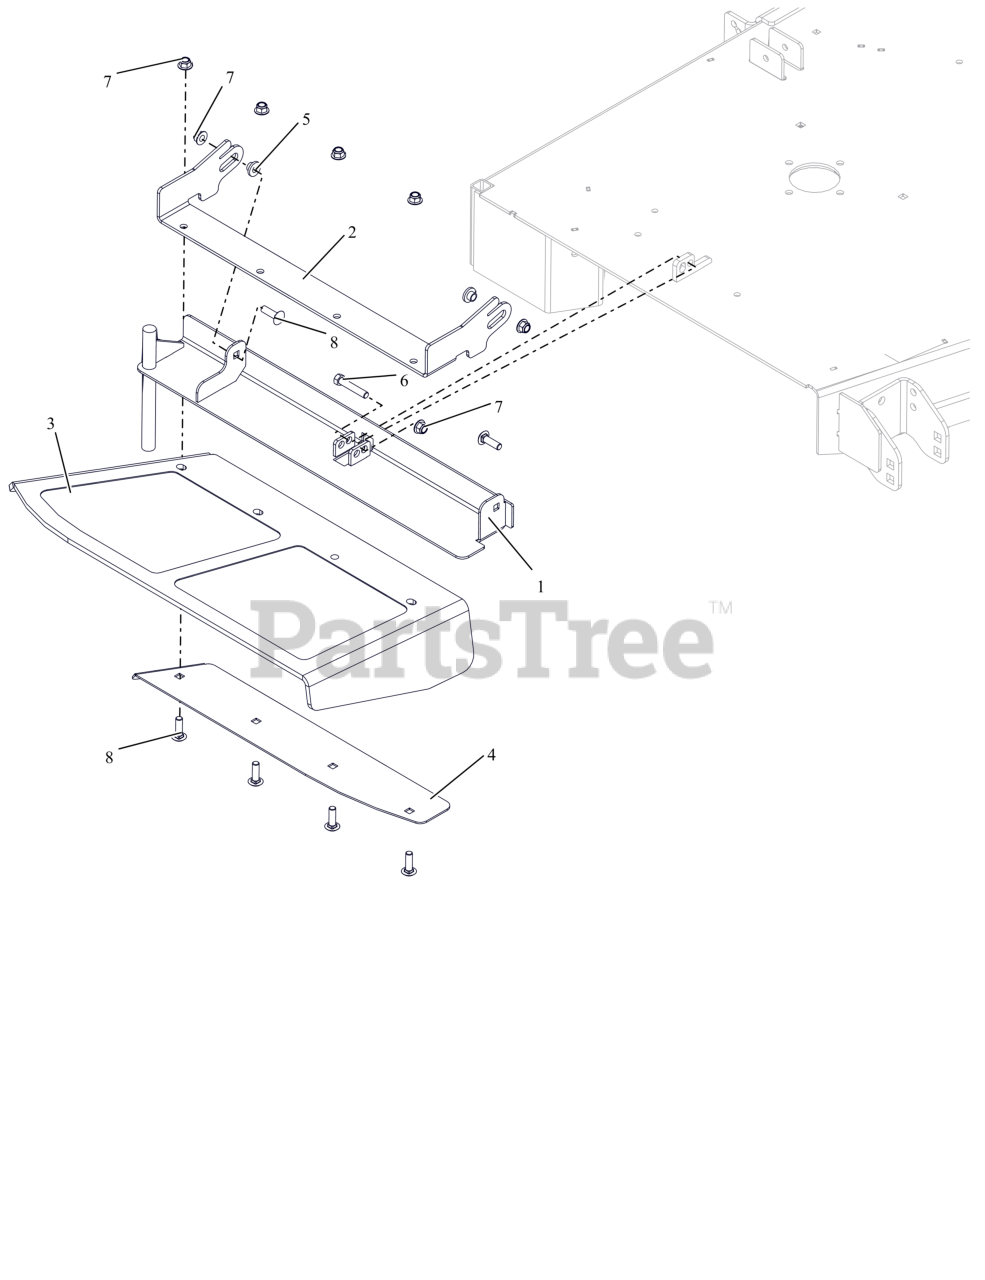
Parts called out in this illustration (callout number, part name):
1	72"DISCH CHUTE MTG WMT W/SAFE
2	72" CHUTE MTG BRKT - RED
3	CHUTE, 72" FORMED RUBBER DISCH
4	72" DISCH CHUTE CLAMP PLT -RED
5	BSHG-FLG .385X.500X.875X.406
6	BLT,HEX .38-16X2.00 G5 ZCC
7	NUT,NYL-FLG .38-16 GF ZCC
8	BLT,RHSSN .38-16X1.25 G5 ZCC
